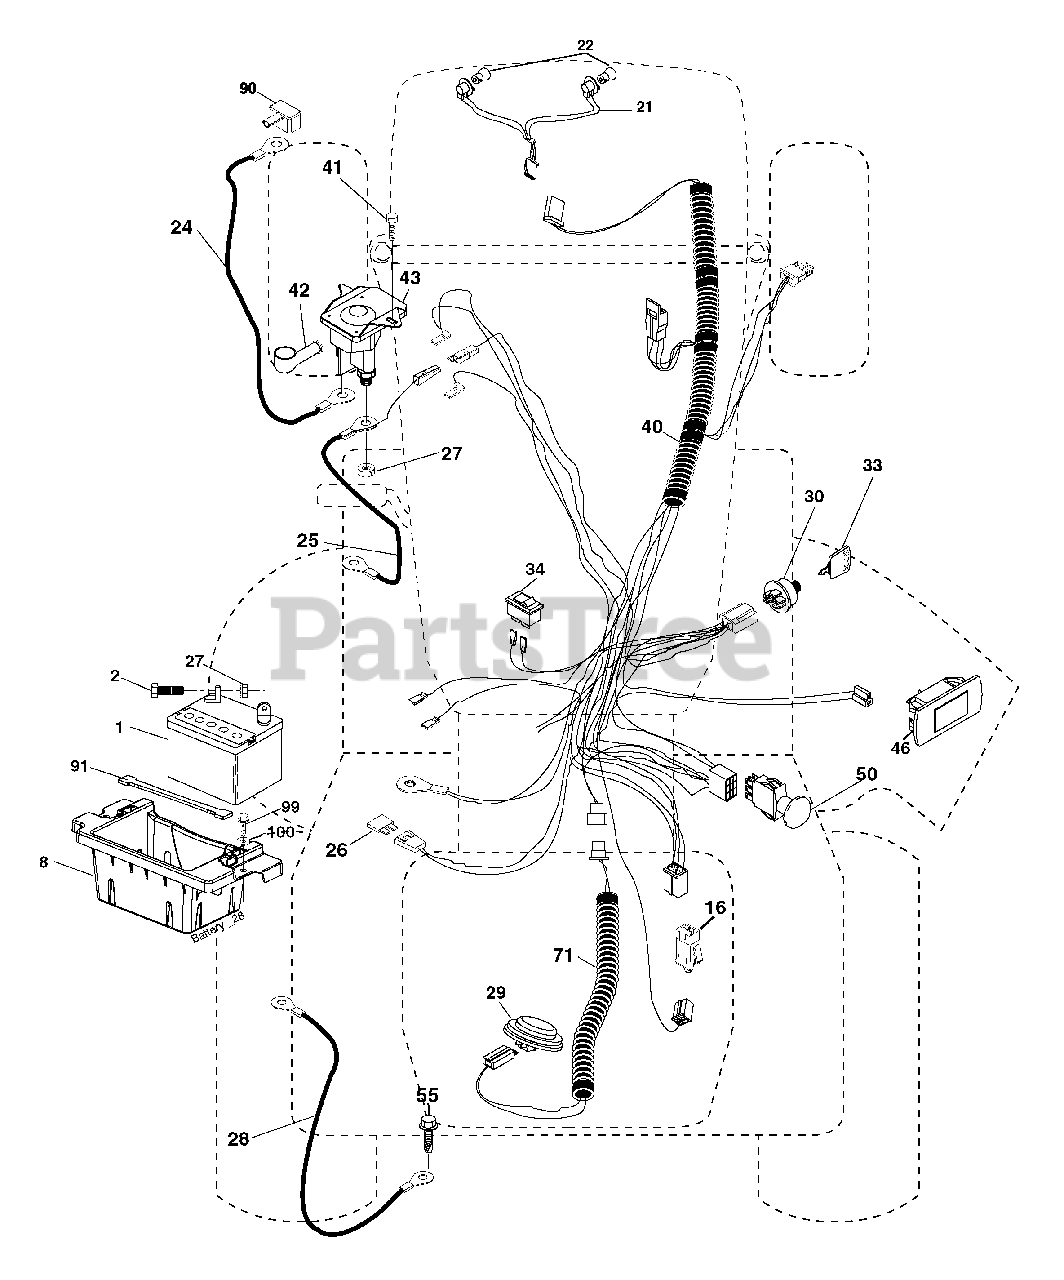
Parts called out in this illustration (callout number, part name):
1	Battery
2	Bolt Hex Head 1/4-20 x 3/4
8	Box Battery
16	Switch Interlock Push-In
21	Harness Socket Light W/4152J
22	Bulb Light
24	Cable Brty
25	Cable Starter
27	Nut Keps Hex 1/4-20 unc
28	Cable, Ground
29	Switch, Seat
30	Switch, Ign
33	Key, Ignition
34	Switch Light / Reset
40	Harness Ign.
41	Screw Thd Cut 1/4-20 x 1/2
42	Cover, Terminal
43	Solenoid
46	Gauge Service reminder Hrmtr
50	Switch PTO
55	Screw Thdrol 5/16-18 x 3/4 TYTT
71	Harness Ign. Dash
90	Cover Terminal
91	Strap Battery Mount Front
99	Screw Hexwsh Thdrol 1/4-20 x 3/4
100	Washer 9/32 x 7/8 x 16 Ga.
